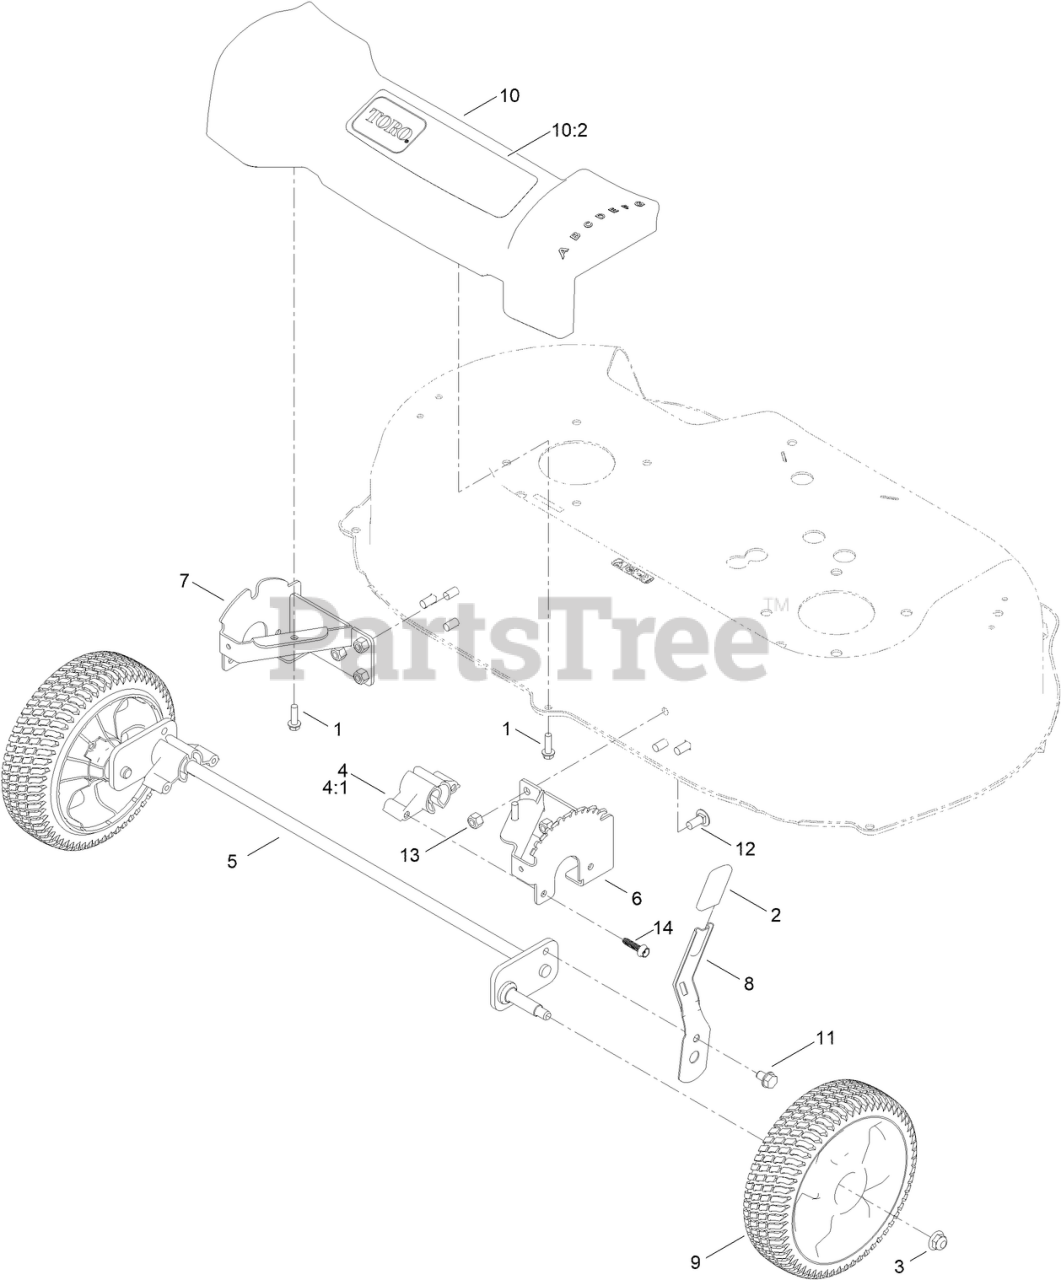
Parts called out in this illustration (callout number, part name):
1	SCREW-HWH
2	GRIP-LEVER
3	NUT-HF, NI
4	BUSHING-PIVOT, FRONT
4:1	RESIN-NYLON 66
5	FRONT AXLE ASM
6	PLATE-HOC, LH
7	PLATE-HOC, RH
8	ARM-SPRING
9	8 INCH WHEEL ASM
10	FRONT COVER ASM
10:2	ARTWORK-TORO TIMEMASTER
11	SCREW-HWH
12	SCREW-CARR
13	NUT-LOCK, NI
14	SCREW-FLANGE, PLASTIC
